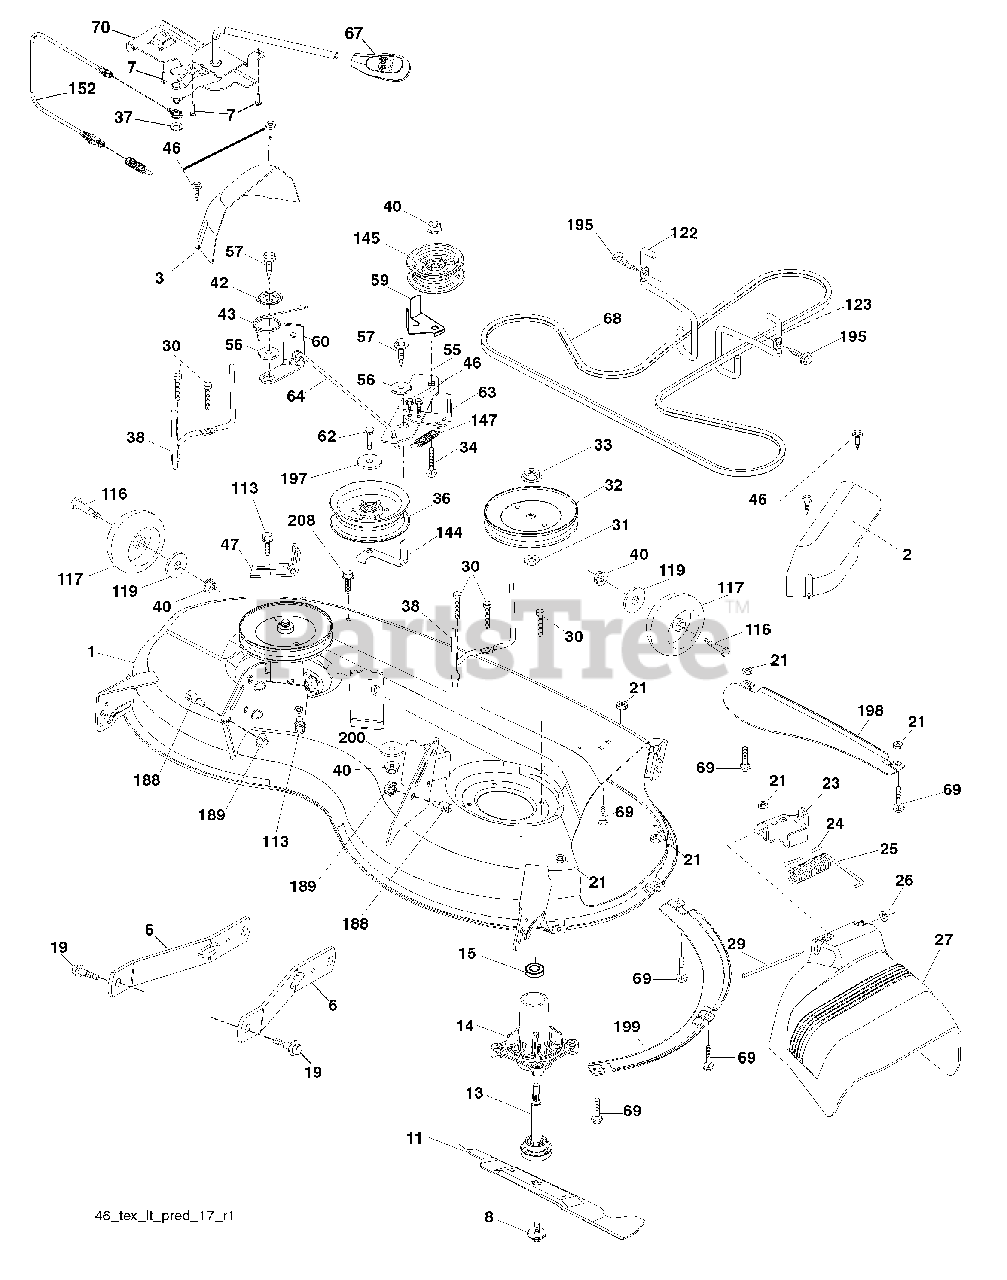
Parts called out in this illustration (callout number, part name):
1	Mower Housing
2	Cover Mandrel RH
3	Cover Mandrel LH
6	Arm Suspension
7	Screw #10 x 0.750
8	Bolt/Washer asm 7/16-20 unf
11	Blade Mower
13	Shaft Assembly, Mandrel
14	Housing, Mandrel
15	Bearing, Ball, Mandrel
19	Bolt, Shoulder
21	Nut
23	Bracket, Deflector
24	Cap, Sleeve
25	Spring, Torsion, Deflector
27	Shield, Deflector
29	Rod, Hinge
30	Screw Thdrol Rolling Wsh Hd
31	Washer, Spacer
32	Pulley, Mandrel
33	Nut, Toplock, Flanged
34	Bolt Carr Sh. 3/8-16 x 1-1/2 Gr. 5
36	Pulley, Idler, Flat
37	Washer 13/32 x 13/16 x 16 Ga.
38	Keeper Belt LH Mandrel
40	Nut, Lock Flg. 3/8-16 unc
42	Spring Trosion Brake
43	Spring Torsion Retainer
47	Bracket Clutch Cable
55	Arm, Idler
56	Spacer, Retainer
57	Screw Hexwsh Thd 3/8-16 x 1
59	Guard, Tuv Idler
60	Arm Brake Mower LH
62	Bolt 3/8-16 unc x 2-1/4 Gr. 5
63	Arm Brake Mower
64	Linkage Brake
67	Handle, Clutch Cable
68	V-Belt
69	Bolt
70	Clutch Asm. Cable
113	Screw 5/16-18
116	Bolt, Shoulder
117	Wheel, Gauge
119	Washer 13/32 x 1-1/4 x 12 Ga.
122	Keeper Belt Eng. LH
123	Keeper Belt Eng. RH
144	Keeper Belt
145	Pulley Idler
147	Spring Return
152	Cable Clutch Manual w/Spr.
188	Stud Fastener
189	Nut Lock Hex Flange
195	Screw 3/8-16 x 3/4
197	Washer 13/32 x 13/16 x 12 Ga.
198	Baffle Center Front
199	Baffle Front RH
200	Washer 13/32 x 1 x 1/2 11 Ga.
208	Screw 3/8-16 x 1/2
208	Mandrel Assembly
208	Replacement Mower, Complete
